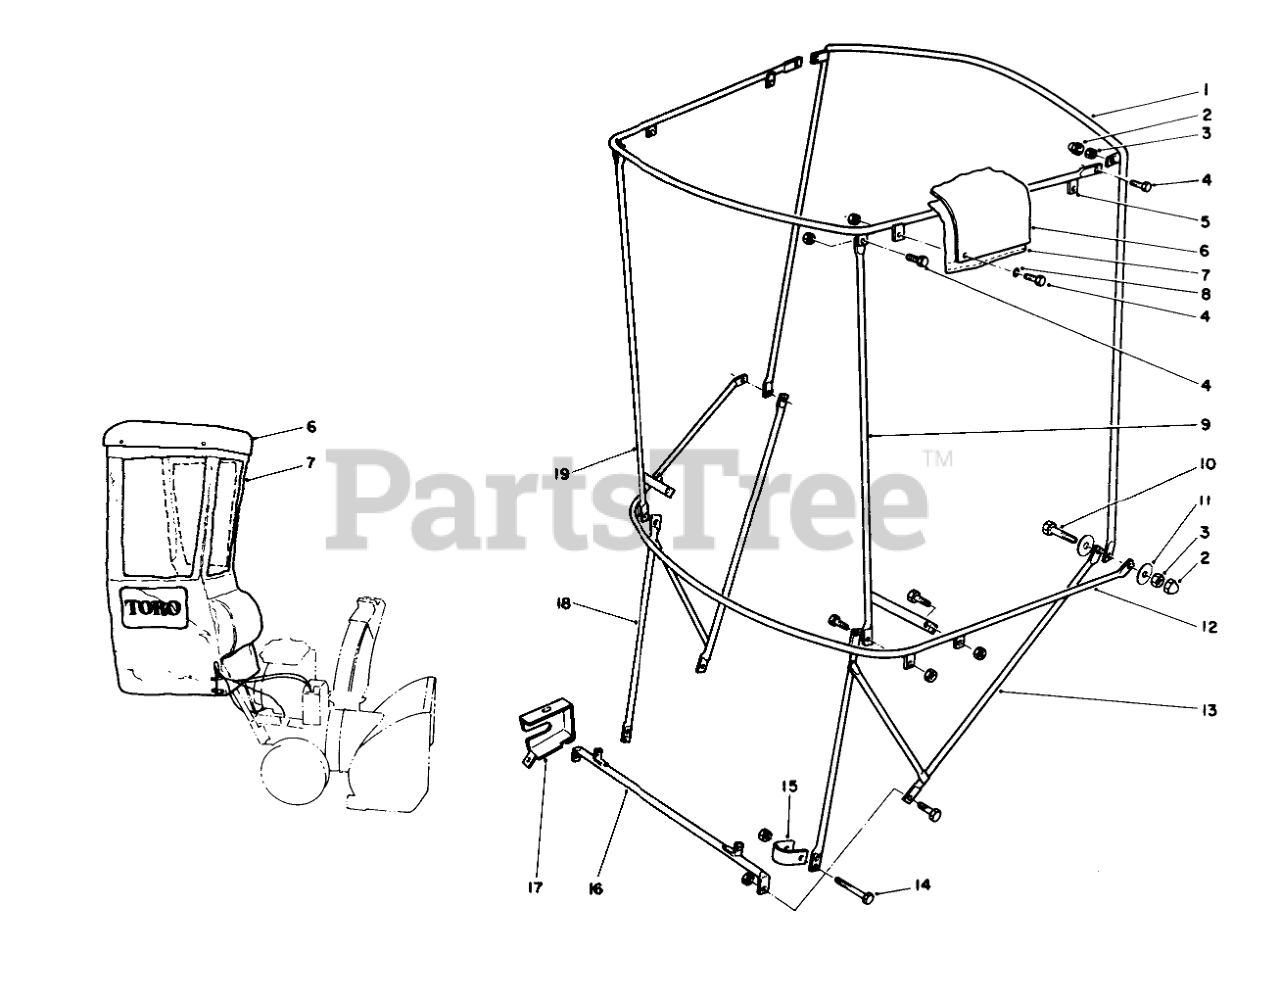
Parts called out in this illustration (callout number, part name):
1	VERTICAL BOW
2	CAPLUG
3	NUT-HEX, SIDE DEFORM
4	SCREW-HH
5	FRAME - TOP
6	Top-Plastic
7	Cover-Vinyl
8	WASHER-FLAT
9	CORNER POST - LH
10	SCREW-HH
11	WASHER-FLAT
12	HORIZONTAL BOW
13	Bracket-LH
14	SCREW-HH
15	CLAMP
16	Bracket-Base
17	COVER-LOCK, LEVER
18	BRACKET-RH
19	CORNER POST - RH
